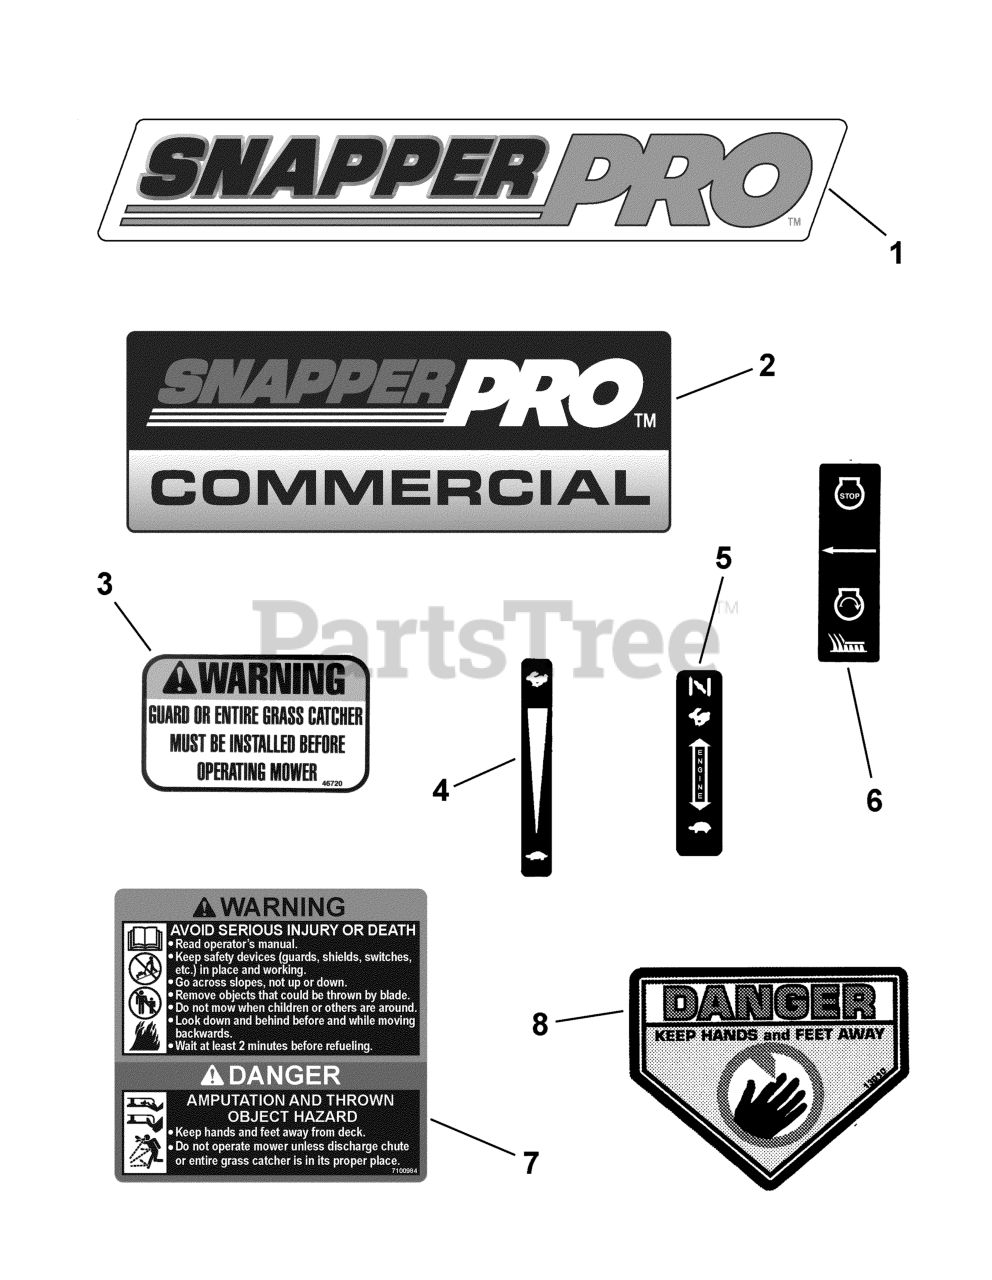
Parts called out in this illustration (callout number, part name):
1	DECAL, Snapper Pro, Heat
2	DECAL, Control Panel, Snapper Pro
3	DECAL, OPC Bail (International Symbol)
4	DECAL, Speed Shift
5	DECAL, Throttle Control, KWV
6	DECAL, Warning/Danger WBM
7	DECAL, Danger, Cut Finger
8	DECAL, Chute/Deflector
